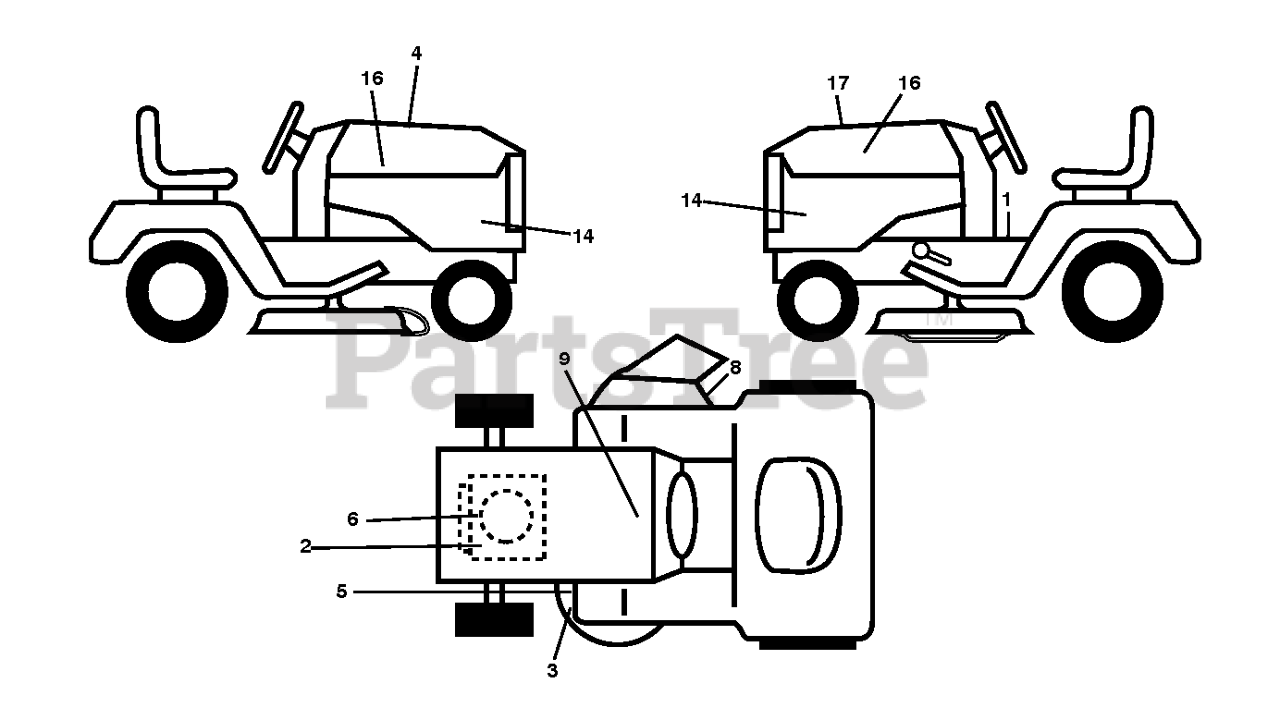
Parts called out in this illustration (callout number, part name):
1	DECAL.FENDER.WARNING.ENG
3	DECAL.WARN.KEEP.HAND.AWAY
4	DECAL.WARNING.CUST.RESP.E85.
5	DECAL.MOWER
6	DECAL.ENG.BS.26 HP.PROF.278955
8	DECAL.MOWER.SCH.48/54
9	DECAL BTRY SYMBOLS
14	DECAL.SDPNL.YTH26V54.HUSQ.X668
16	DECAL.BADGE.170MM.TEXTLOGO.
